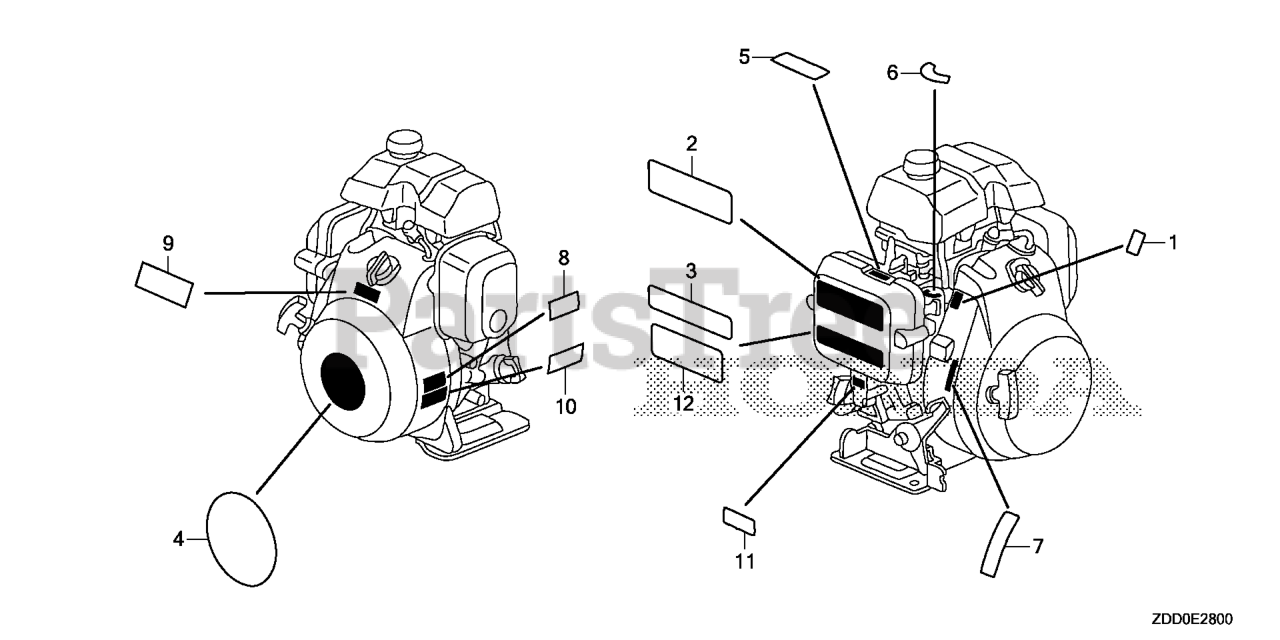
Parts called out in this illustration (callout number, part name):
2	MARK, OPER CAUTION
5	MARK, CHOKE INDICATION
9	MARK, EX. CAUTION (ENGLISH)
11	MARK, TYPE (KRC6)
